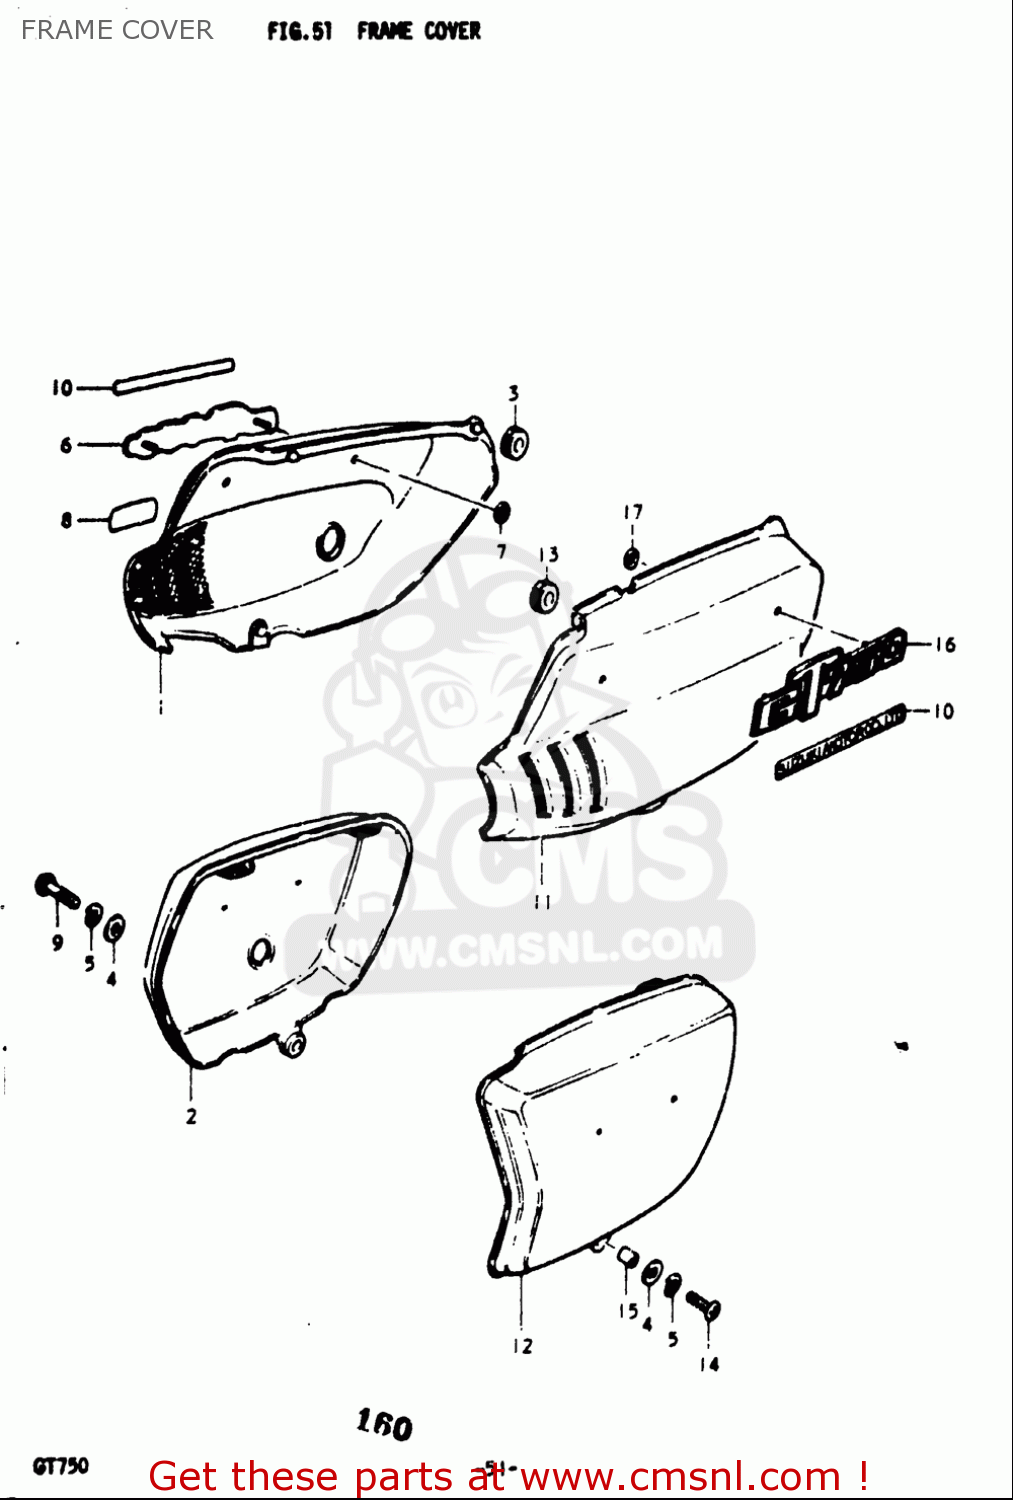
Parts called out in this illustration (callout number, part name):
1	COVER SET,FRAME,R
2	COVER,FRAME,RIGHT
3	CUSHION
4	WASHER(6.5X18X1.6)
5	WASHER,LOCK
6	EMBLEM,FRAME COVER,R
7	NUT
8	EMBLEM,CCIS
9	SCREW
11	COVER SET,FRAME,L
13	CUSHION
14	SCREW
15	SPACER(6.1X9X7.5)
16	EMBLEM,FRAME COVER,R
17	NUT
